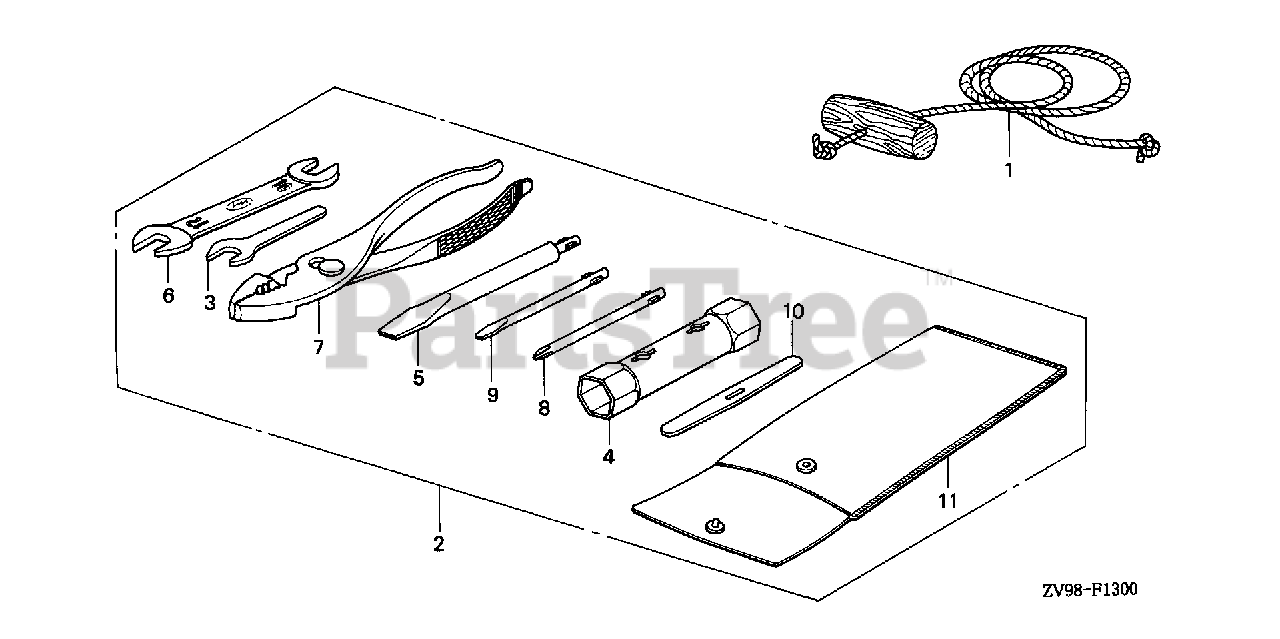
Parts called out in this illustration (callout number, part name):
1	ROPE, STARTER
3	SPANNER (8MM) (NOT AVAILABLE)
4	WRENCH, BOX (P18X19) (NOT AVAILABLE)
5	SCREWDRIVER, CHECK BOLT
6	SPANNER (10X12)
7	PLIERS (135) (KOWA)
7	PLIERS (135)
8	DRIVER 1, PLUS SCREW (NO.2)
9	DRIVER 3, MINUS SCREW (NO.2)
